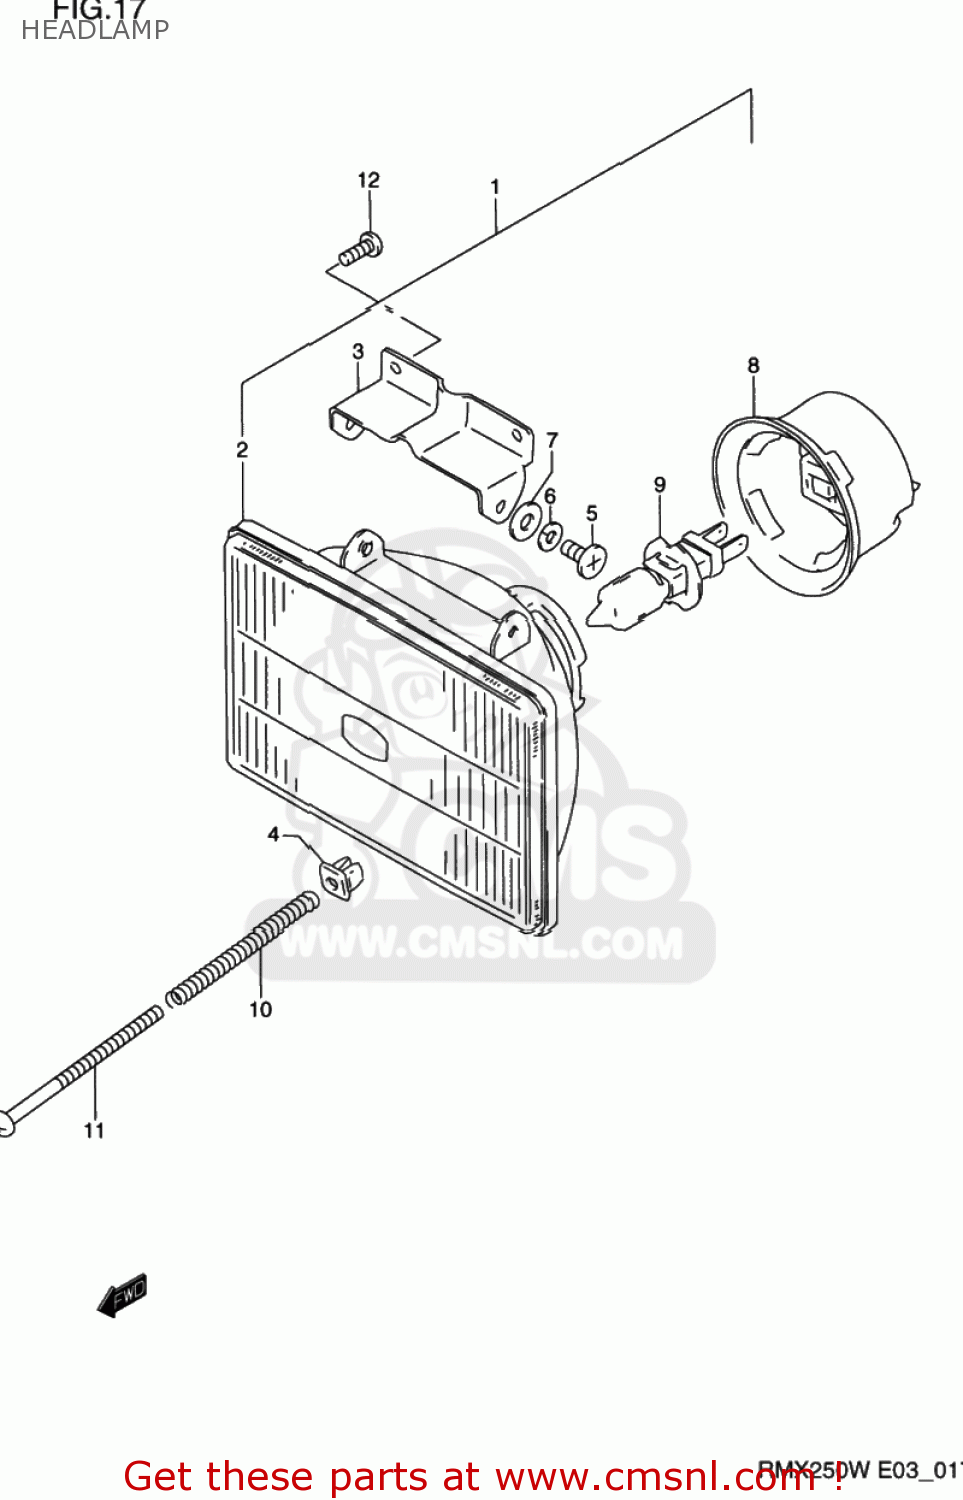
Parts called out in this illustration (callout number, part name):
1	HEADLAMP ASSY
2	UNIT,LAMP
3	BRACKET,LAMP
4	NUT,ADJUSTING
5	SCREW
6	WASHER,LOCK
7	WASHER
8	COVER,SOCKET
9	BULB(12V55W)
10	SPRING,HEAD LAMP ADJUSTER
11	SCREW(4X45)
12	SCREW
